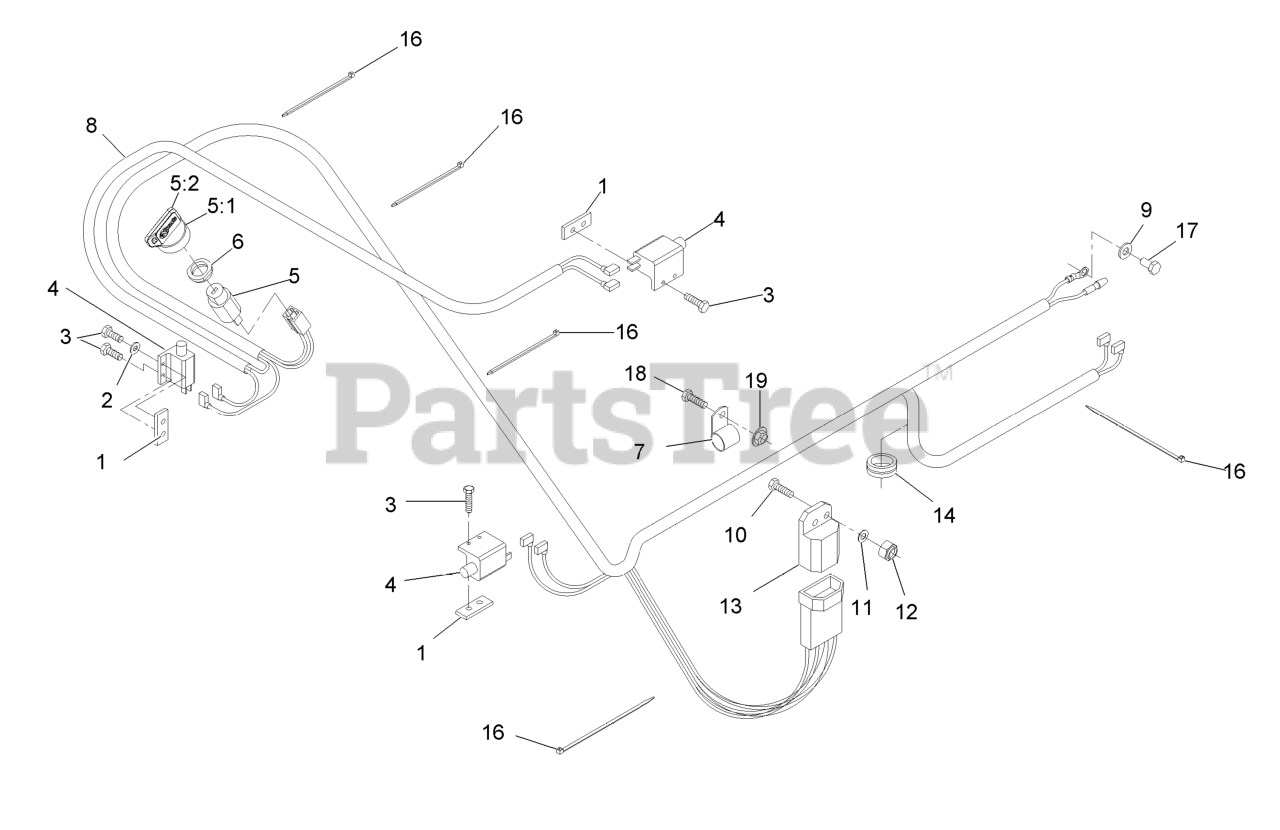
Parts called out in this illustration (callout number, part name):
1	PLATE-TAPPED
2	WASHER-FLAT
3	SCREW-PPH
4	SWITCH-OPEN, NORMALLY
5	SWITCH & KEY (INCLUDES NU
5:1	KEYS-IGNITION (SPARE PAIR
5:2	KEY-IGNITION
6	NUT-SWITCH, IGNITION
7	CLIP-LOOM
8	HARNESS-WIRING
9	WASHER-PLAIN
10	SCREW-HH
11	WASHER-FLAT
12	NUT-LOCK, NI
13	MODULE-INTERLOCK
14	GROMMET
16	TIE-CABLE
17	SCREW-HH
18	SCREW-HH
